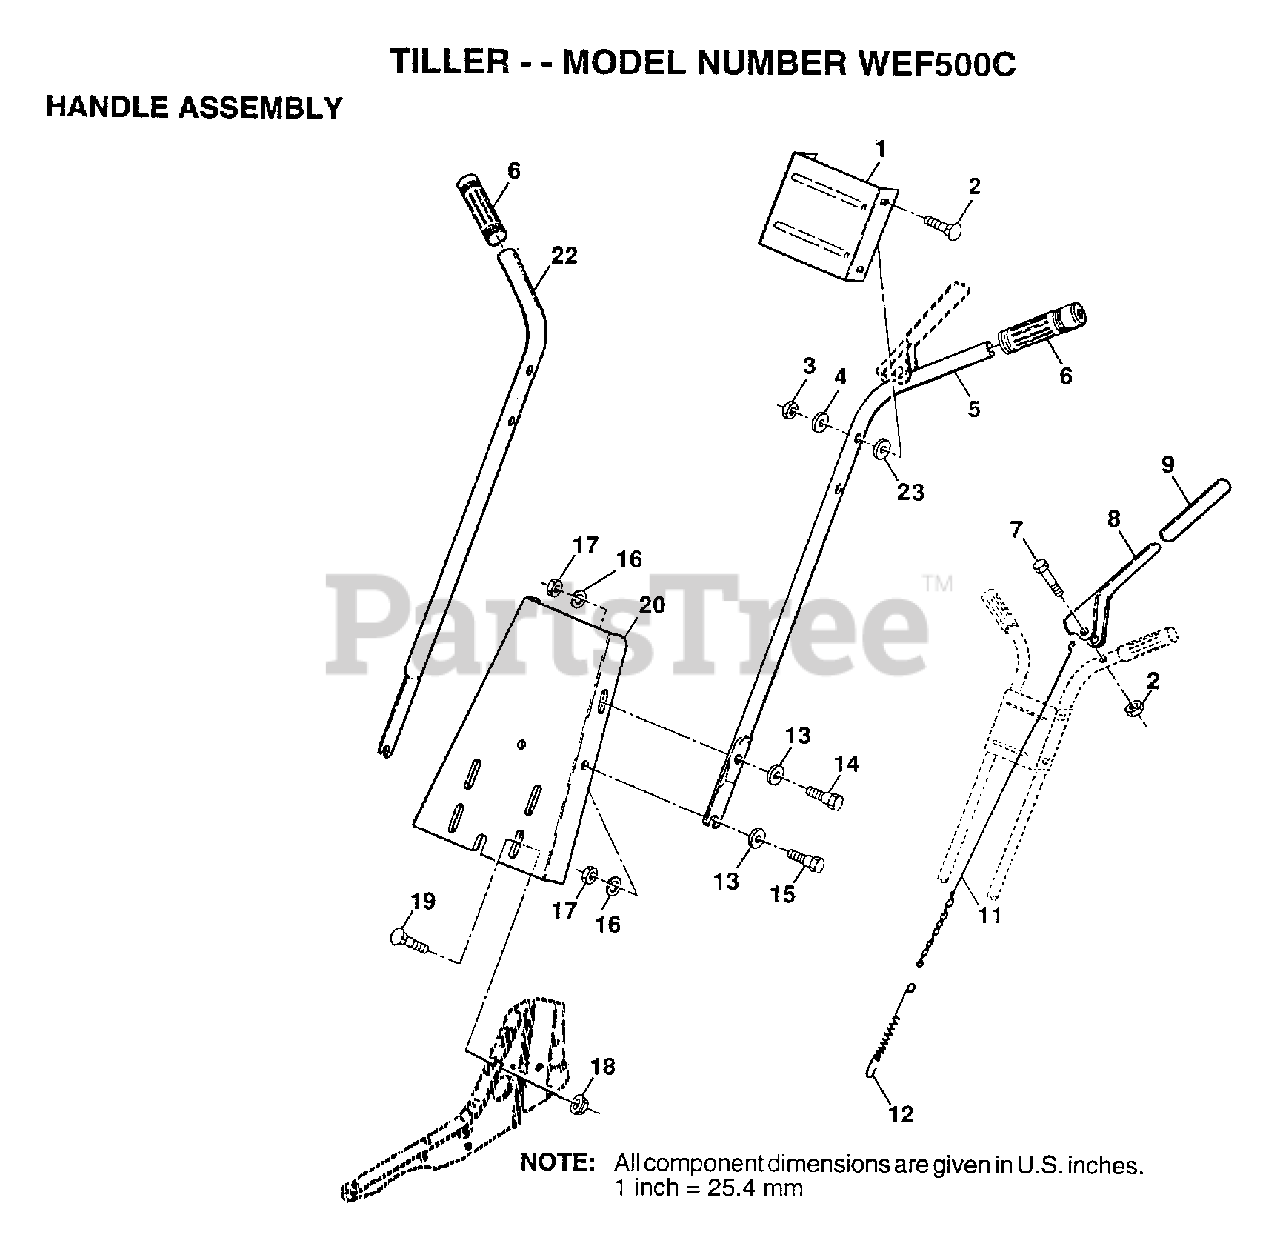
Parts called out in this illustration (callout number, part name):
1	PANEL.CNTRL.HDLE.
2	BOLT
4	WASHER
5	HANDLE LH
7	BOLT.HEX.5/16-1.5
9	GRIP T
12	SPRING EXT TI
13	WASHER
15	BOLT
16	LOCKWASHER
17	NUT.HEX.5/16-18
18	NUT
19	BOLT
20	PANEL.HANDLE.TILL
22	HANDLE RH
23	WASHER
